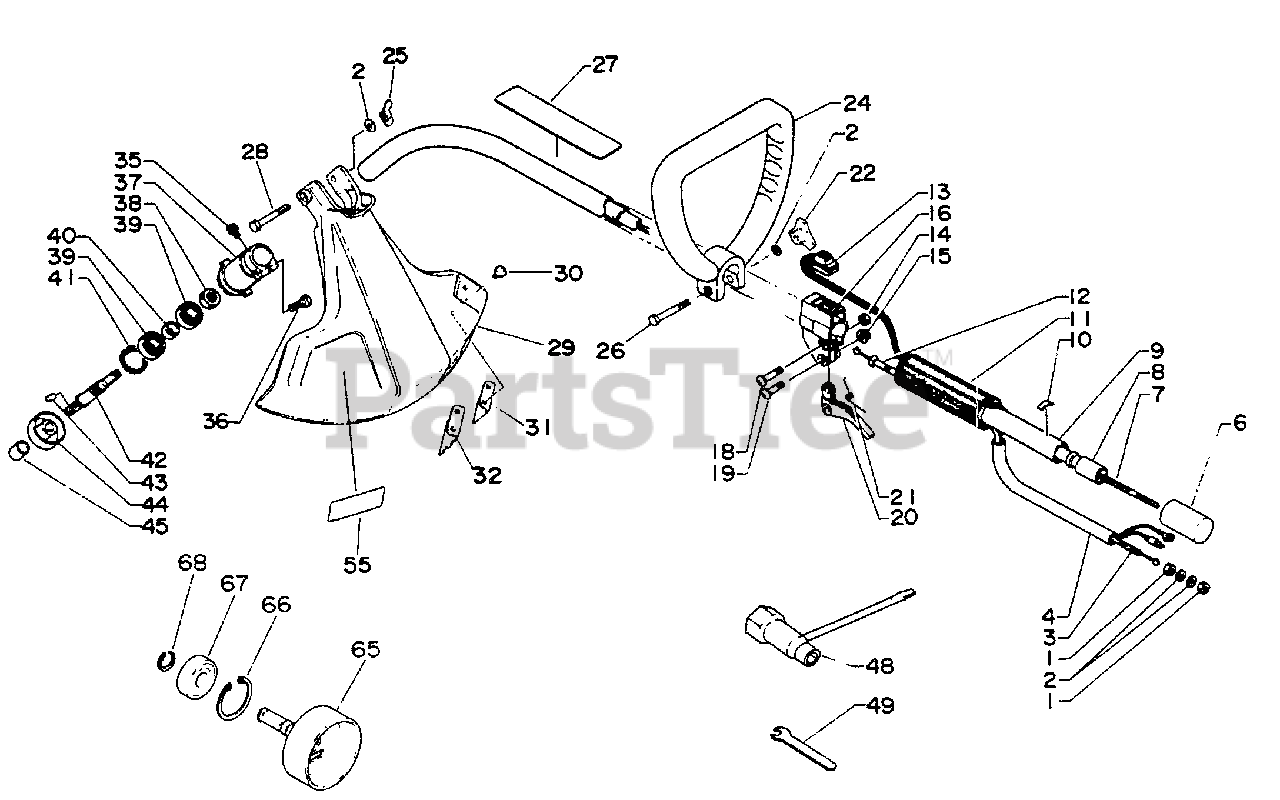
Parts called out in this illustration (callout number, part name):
2	WASHER - 6
3	CABLE, THROTTLE
4	TUBE - VINYL
6	LABEL - GENERATOR
7	DRIVESHAFT - FLEXIBLE
8	BUSHING
9	PIPE, MAIN
10	LABEL - ALIGNMENT
11	GRIP, HANDLE
12	GUIDE, CABLE
13	IGNITION SWITCH ASSY
15	LOCKNUT - 5
16	BRACKET, THROTTLE
18	SCREW - 5X28
19	SCREW - 5X30
20	TRIGGER, THROTTLE
21	SPRING, TRIGGER
22	KNOB, FASTENER
24	HANDLE
25	WINGNUT - 6
26	BOLT - 6X40
27	LABEL - CAUTION
28	BOLT - 6X50
29	SHIELD, DEBRIS - PLASTIC
30	SCREW - 5X16
31	KNIFE, TRIMMER LINE
32	GUARD
35	SCREW - 4X10
36	BOLT - 5X25
37	CASE, GEAR
38	NUT - 12 -- LEFT HAND
39	BEARING, BALL - 6001 DDU
41	RING, RETAINING - 28
42	GEAR - SHAFT
43	PIN - 3X6
44	ADAPTOR, BLADE - UPPER
45	LABEL - GENERATOR
48	T-WRENCH - 8X19mm
49	SPANNER - 10mm
55	LABEL - ECHO
65	DRUM, CLUTCH
66	RING, RETAINING - 32
67	BEARING, BALL - 6201
68	RING, RETAINING - 12
